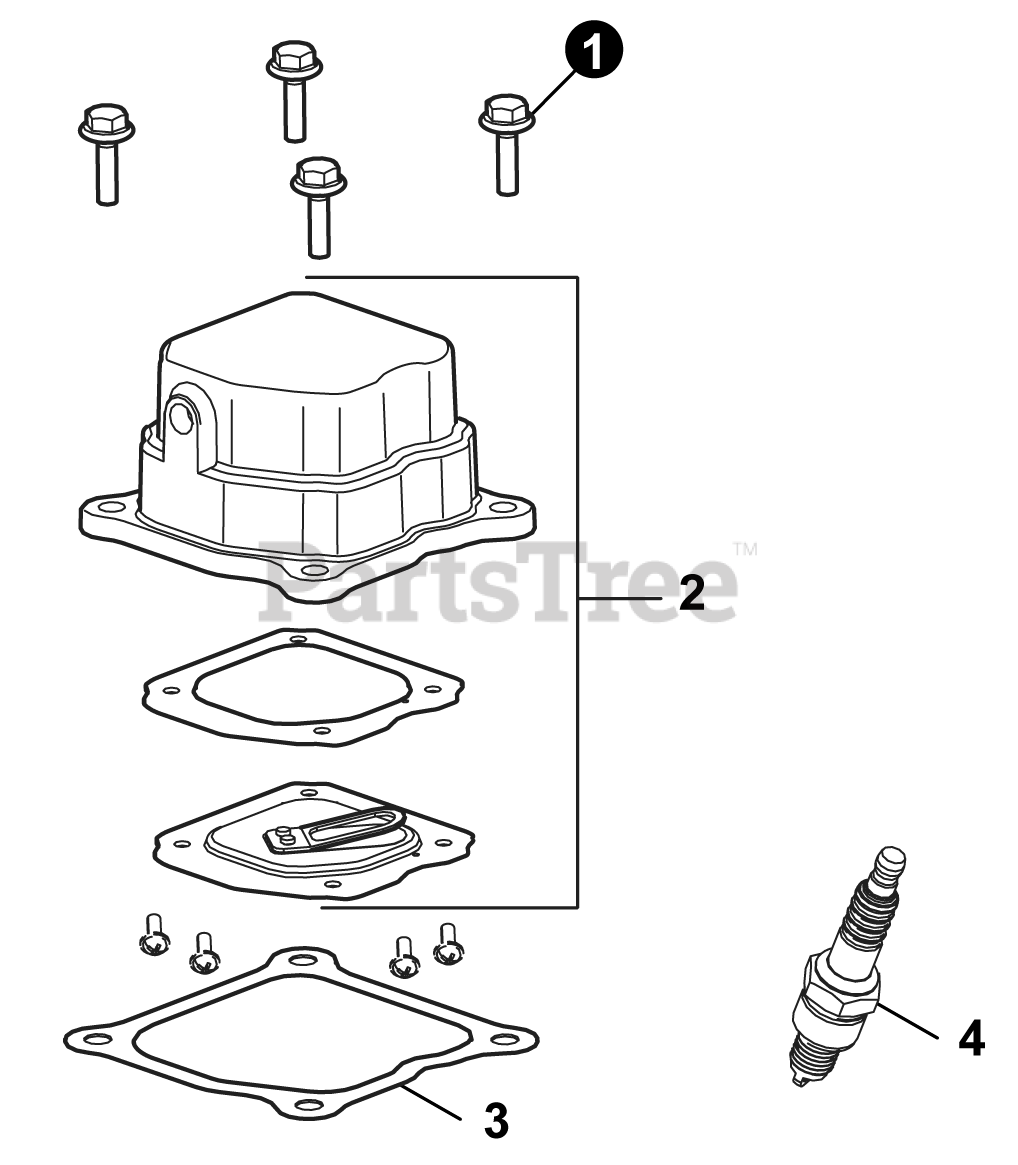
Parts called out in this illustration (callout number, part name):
2	VALVE COVER ASSEMBLY
3	GASKET, VALVE COVER
4	SPARK PLUG
